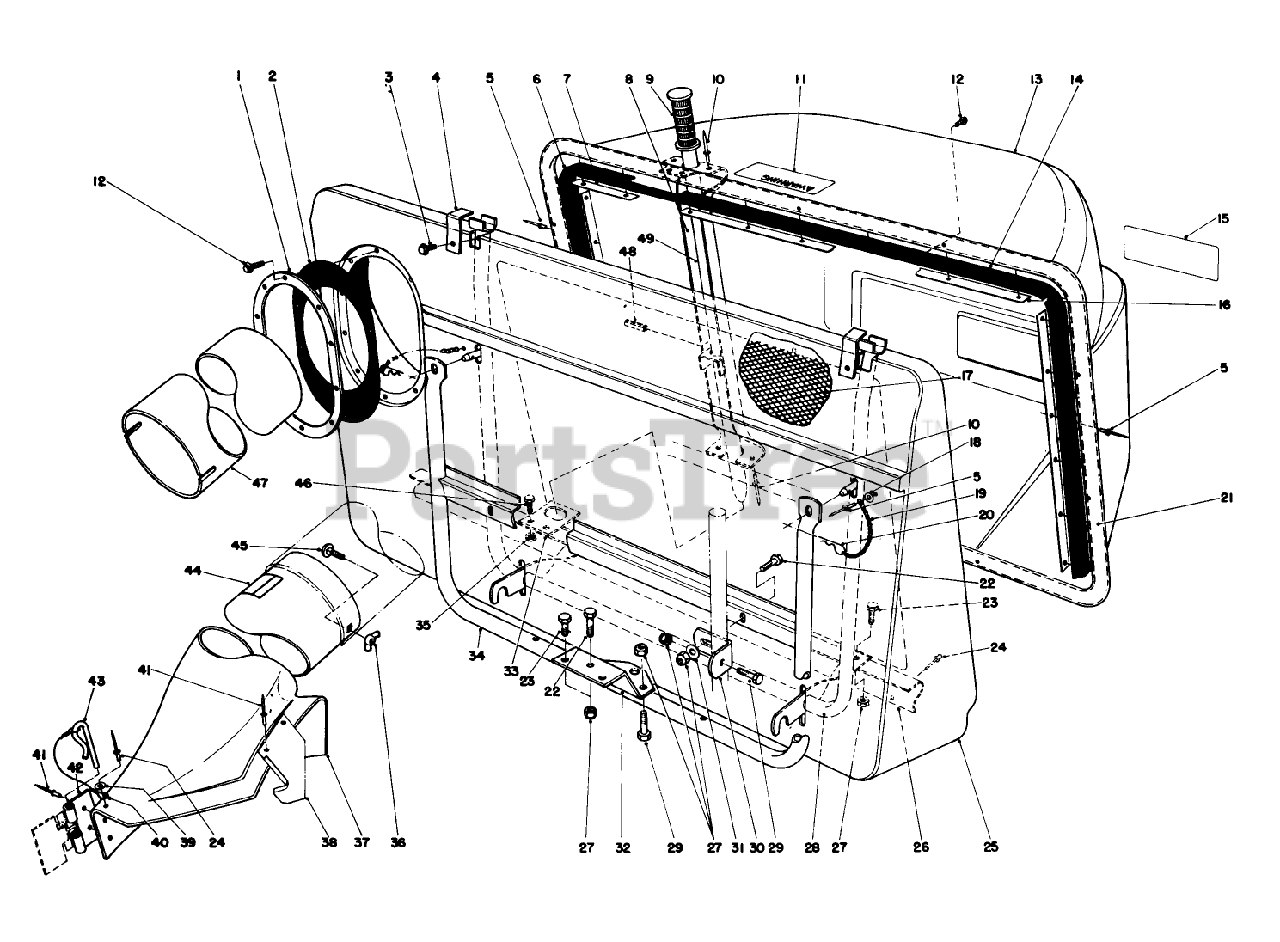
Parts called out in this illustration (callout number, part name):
1	RING-RETAINING
2	RING-RETAINER, RUBBER
3	Hex Hd. Tap Screw
6	RH BAG SEAL
12	SCREW-HWHTF
18	WASHER
20	PIN-HAIR
22	SCREW-HH
23	SCREW-HH
24	RIVET-BLIND
27	NUT-LOCK, CONE
29	SCREW-HH
31	WASHER-PLAIN
32	MTG PLATE *B
34	BAG SUPPORT WA *
35	NUT-LOCK, CONE
36	NUT-WING SPECL
37	CHUTE ASM
38	CHUTE SUPT BRKT
39	WASHER-PLAIN
40	LANYARD
41	RIVET-BLIND
42	BRACKET-MOUNTING, CHUTE
43	PIN-LOCKING, CHUTE
45	BOLT-CARR
46	SCREW-HH
48	PIN-ROLL
49	DUMP HANDLE ASM
